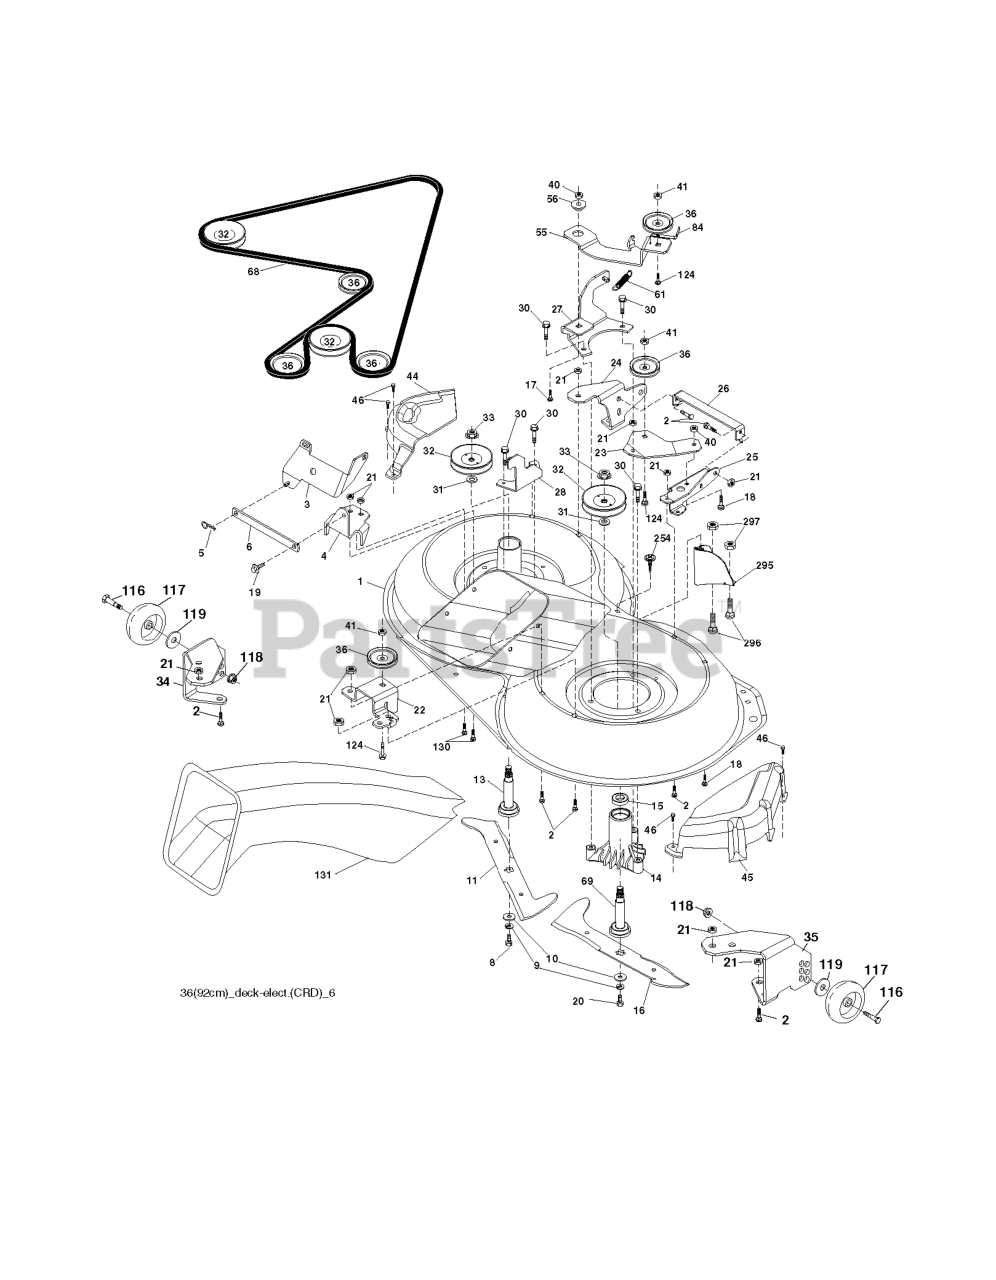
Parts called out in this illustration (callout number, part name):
2	RP BOLT 5/16-18 X3/4 ZN/YEL GR
5	RETAINER-SPRNG RB
6	BAR.SWAY.92.CRD
8	BOLT.3/8-24X1.25 GR8
9	LOCKWASHER
10	WASHER.BLADE
13	SHAFT ASM VENT
14	HOUSING.MANDREL.VENTED (MACHD)
17	BOLT.3/8-14X1.25
19	BOLT SHD 5/16-18
20	BOLT.3/8-24X1.25GR8. LHTHRD
21	LOCKNUT
26	SUPPORT
30	SCREW, WASHER HEAD
31	WASHER.SPACER.MANDREL
32	PULLEY MANDREL
33	NUT.FLANGE.LOCK.TOP
36	PULLEY.IDLER.4.25
41	NUT LOCK FLG 3/8-16 UNC
45	COVER.MANDREL.RH.CRD
46	SCREW.1/4-20X5/8
55	ARM.IDLER.92 CRD.2006
56	SPACER.RETAINER.MOWER
61	SPRING.TENSION.BELT
68	BELT.DRIVE.92CM.CRD.2006
69	SHAFT.ASM.W/LWR.BRG.RH.THREAD
84	KEEPER, BELT IDLER
116	BOLT.SHOULDER.3/8-16X3-5/8.
117	RP WHEEL. GUAGE RALLY
118	LOCKNUT
119	WASHER
124	BOLT.3/8-16X1.50
130	BOLT.CARR.SQNK.5/16-18UNC.X3/4
131	CHUTE BAGGER
254	SCREW 3/8-16X1
296	BOLT
297	NUT CENTERLOCK
